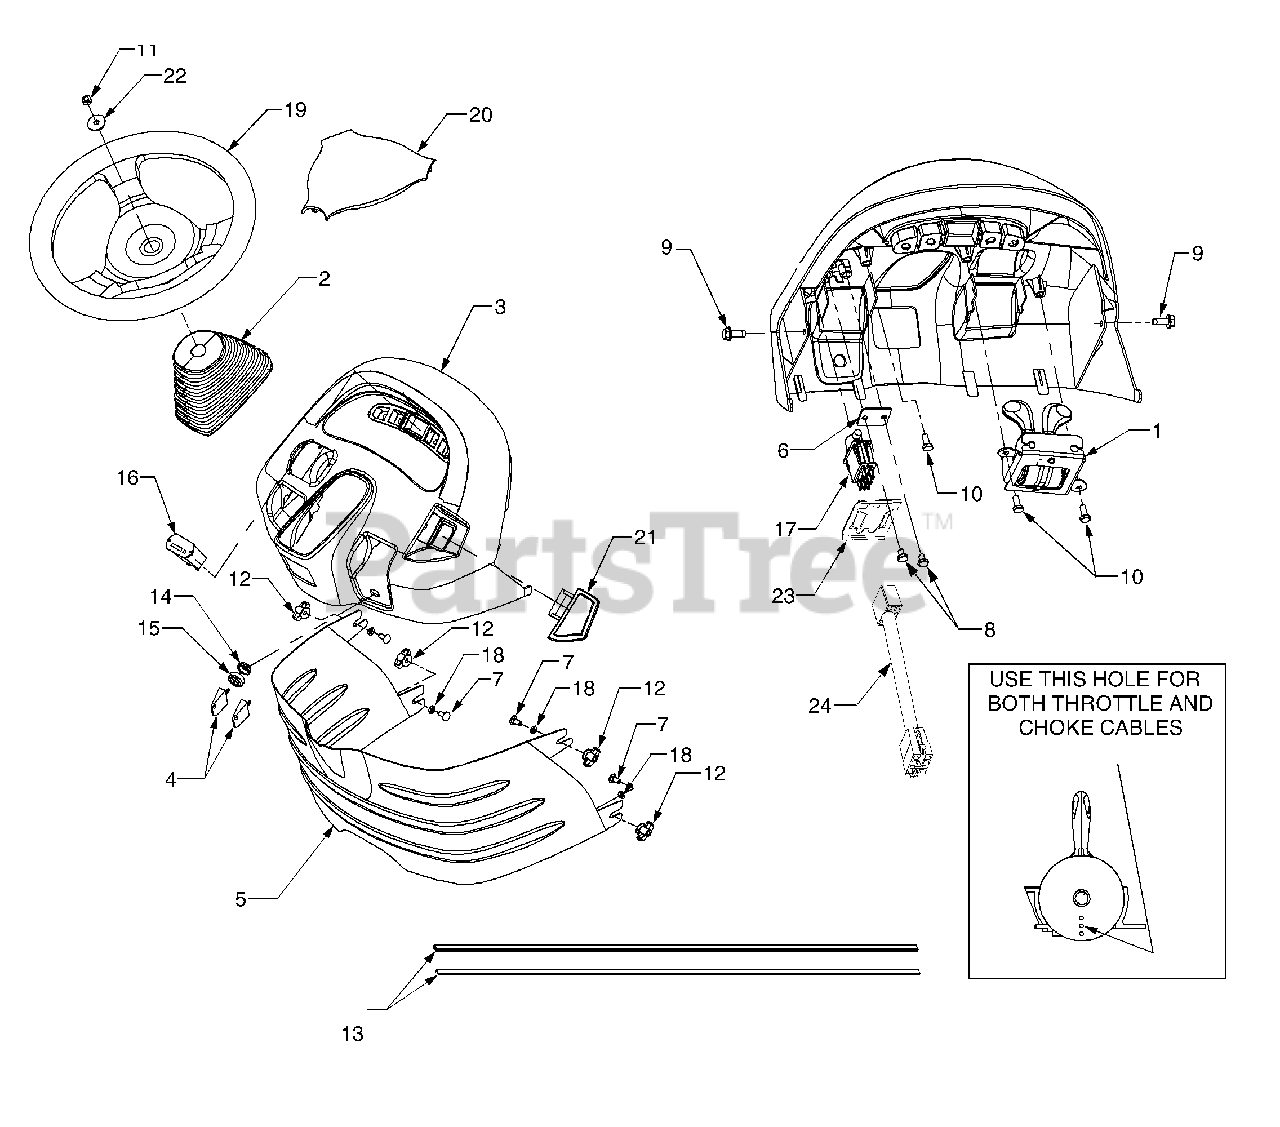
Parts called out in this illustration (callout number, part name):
1	Control Assembly, Throttle/Choke
2	Boot, Tilt Steer
3	Dash Panel
4	Key, Ignition (Set of 2)
7	Carriage Bolt, 1/4-20 x .62
8	Screw, Hex Cap 1/4-20 x .375 GR5
9	Screw, Hex Wash Hd. Tapp 5/16-18 x .75
10	Screw, Hex Cap 1/4-20 x .50 GR5
11	Nut, Hex Lock, 5/16-24
12	Wing Nut, 1/4-20 w/Bell Washer
13	Seal, Screen
14	Nut, Ignition Switch, 5/8-32
15	Cap, Ignition Switch
16	Hour Meter
17	Switch, PTO
18	Nut, Push
19	Steering Wheel
20	Cover, Steering Wheel
21	Handle, PTO Switch
22	Washer, Flat, .34 x 1.5 x .10
23	Bracket, PTO Switch Retainer
24	Harness, PTO Adapter
